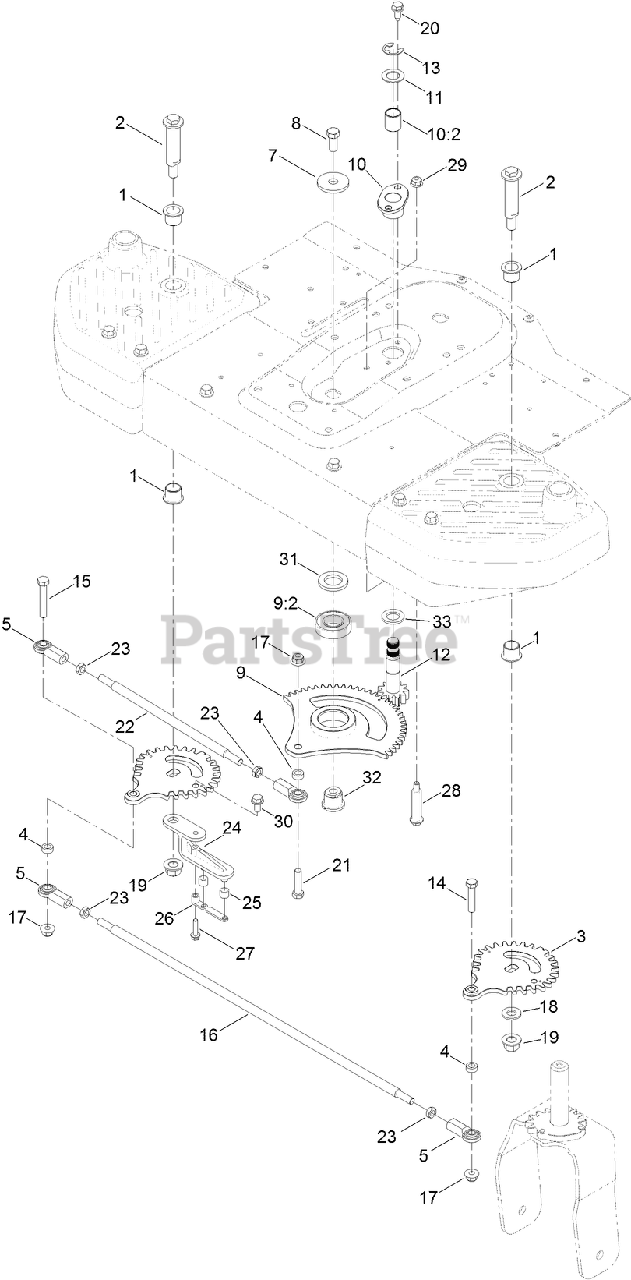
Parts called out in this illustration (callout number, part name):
1	BEARING-FLANGE, IGLIDE
2	BOLT-SHOULDER
3	GEAR-WHEEL, 30 TOOTH
4	SPACER
5	JOINT-BALL, END
7	WASHER-THRUST
8	SCREW-HH
9	SECTOR GEAR ASM
9:2	BEARING-BALL
10	FLANGE BEARING ASM
10:2	BUSHING-STRAIGHT
11	WASHER-THRUST
12	LOWER STEERING SHAFT ASM
13	E-RING
14	SCREW-HH
15	SCREW-HH
16	ROD-CROSS, WIDE
17	NUT-HF, NI
18	WASHER-FLAT
19	NUT-LOCK
20	SCREW-HWHTF
21	SCREW-HH
22	ROD-STEERING, WIDE
23	NUT-HJ
24	LEVER-CABLE
25	BUSHING
26	STRAP-ROLLER
27	SCREW-HWHTF
28	BOLT-SHOULDER
29	NUT-HF, NI
30	SCREW-HWHTF
31	SPACER-BEARING
32	PIVOT-BEARING
33	WASHER
